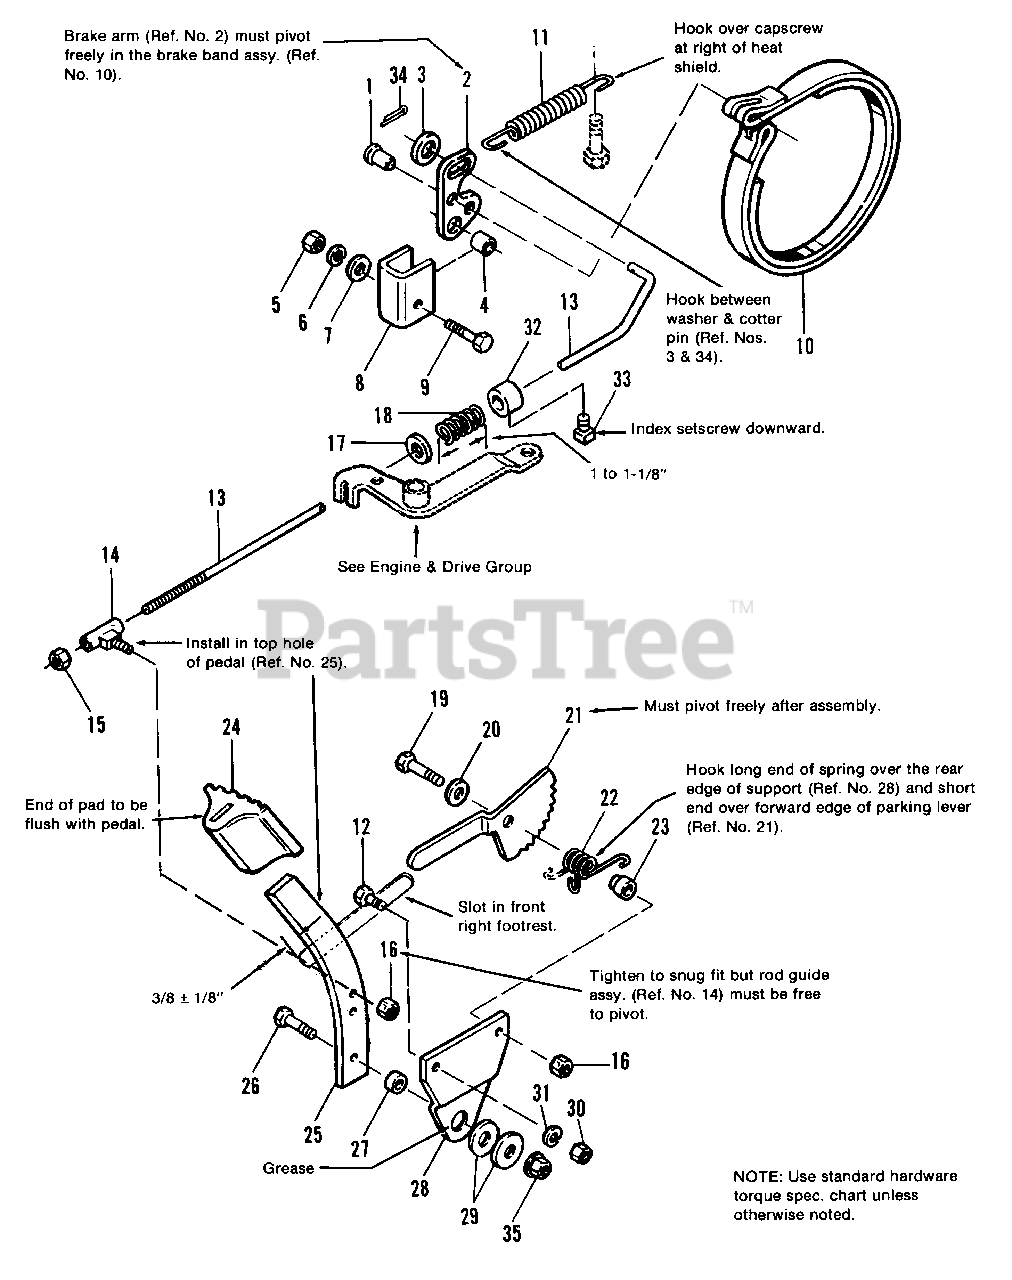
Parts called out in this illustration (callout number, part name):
2	ARM, Brake
3	WASHER, Plain, 11/32
5	NUT, Hex, 3/8-16
6	LOCKWASHER, 3/8
7	WASHER, Plain, 11/32
8	BRACKET, Brake
9	CAPSCREW, Hex Hd., 3/8-16 x 1-3/4
10	BRAKE BAND ASSY.
12	CAPSCREW, Hex Hd., 5/16-18 x 3/4
13	ROD, Brake
14	ROD GUIDE ASSY.
15	LOCKNUT, Esna, 5/16-18
16	LOCKNUT, Hex, 5/16-18
17	WASHER, Plain, 13/32 x 1
19	CAPSCREW, Hex Hd., 5/16-18 x 1-1/2
20	WASHER, Plain,11/32
21	LEVER, Parking Brake
22	SPRING Torsion
25	PEDAL, Brake
26	CAPSCREW, Hex, 3/8-16 x 1-1/4
28	SUPPORT, Pedal
29	WASHER
30	NUT, Hex, 5/16-18
31	LOCKWASHER, 5/16
32	COLLAR, Set
33	SCREW, Set, Sq. Hd., Cup Pt., 1/4-20 x 3/8
34	PIN, Cotter
35	NUT, Hex Flangelock, 3/8-16
